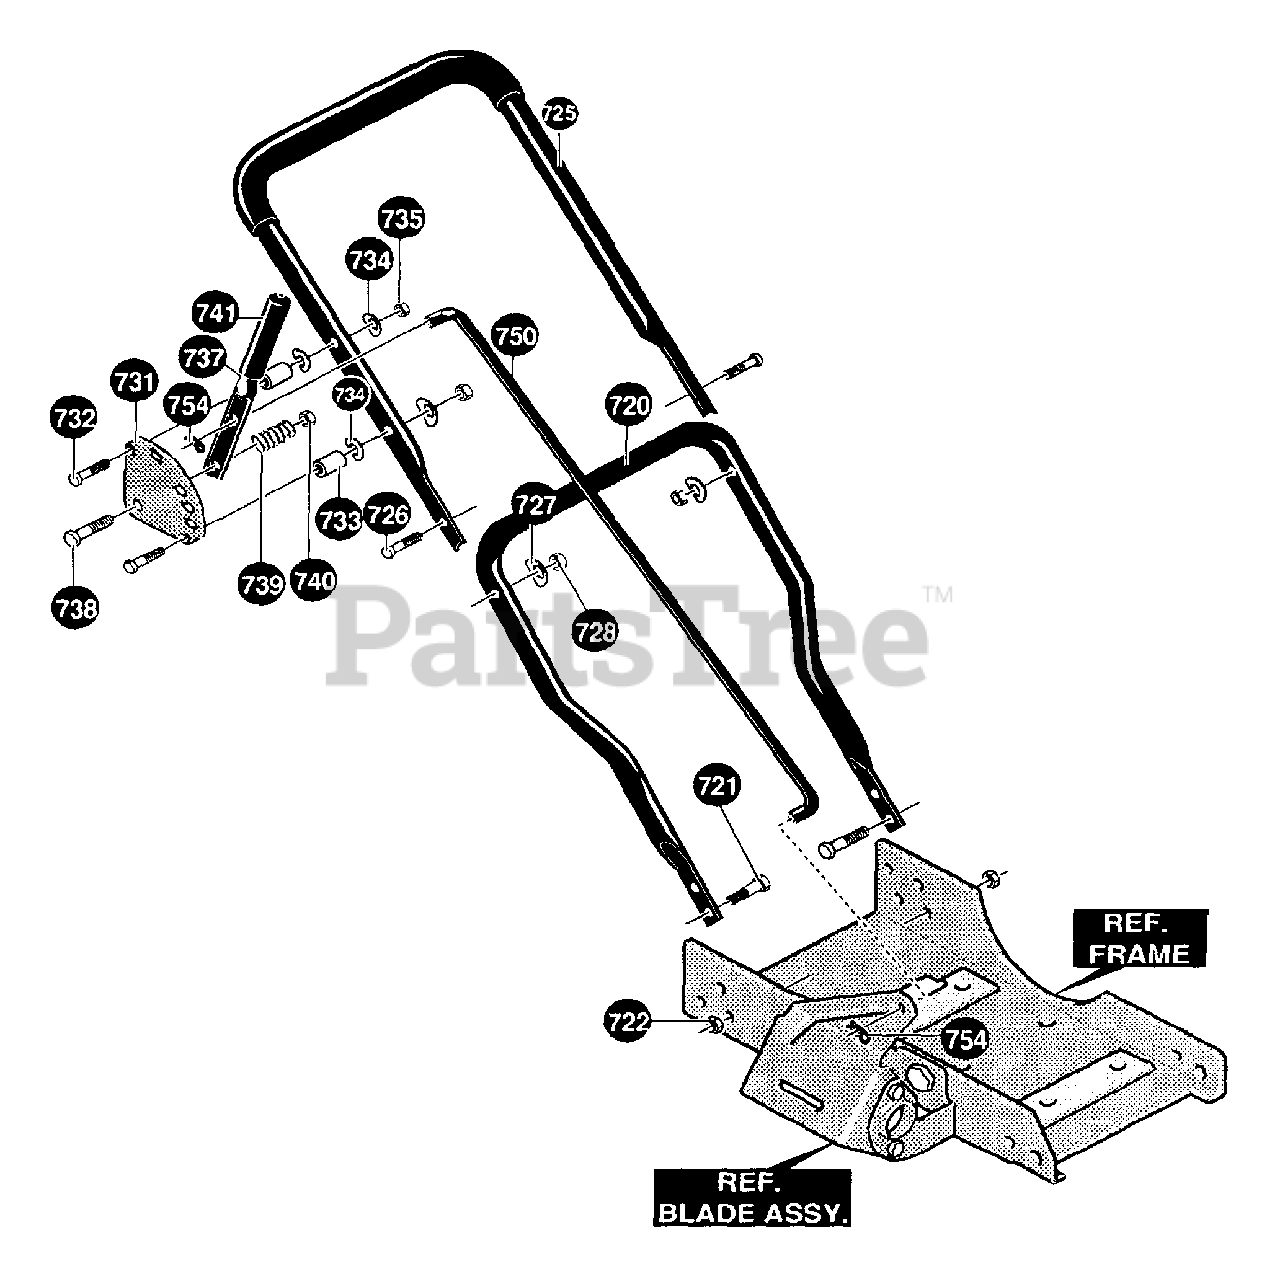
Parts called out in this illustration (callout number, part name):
720	HANDLE, LOWER 7/8
721	SCREW, 5/16-18X1.00 HHC
722	NUT, 5/16-18 REGHEXCTRLK
725	HDLE, UPPER W/FOAM
726	SCREW, 5/16-18X1.75 HHC
727	WASHER, .3431DX1.0X.062 FORM
728	NUT, 5/16-18 REGHEXCTRLK
731	PLATE, QUADRANT SHIFT/ENGAG
732	SCREW, 1/4-20X2.00 HHC
733	SPACER, SLEV .281X.50X.68
734	WASH ER, .3431DX1.0X.062 FORM
735	NUT, 1/4-20 REGHEXCTRLK
737	HANDLE, DEPTH ADJUST
738	SCREW, 5/16-18X1.25 HHC
740	NUT, 5/16-18 REGHEXCTRLK
741	GRIP, HAND .75X4.87
750	ROD, DEPTH CONTROL 30.0 LG
754	PIN, HAIR .072 DIA X1.13LG
